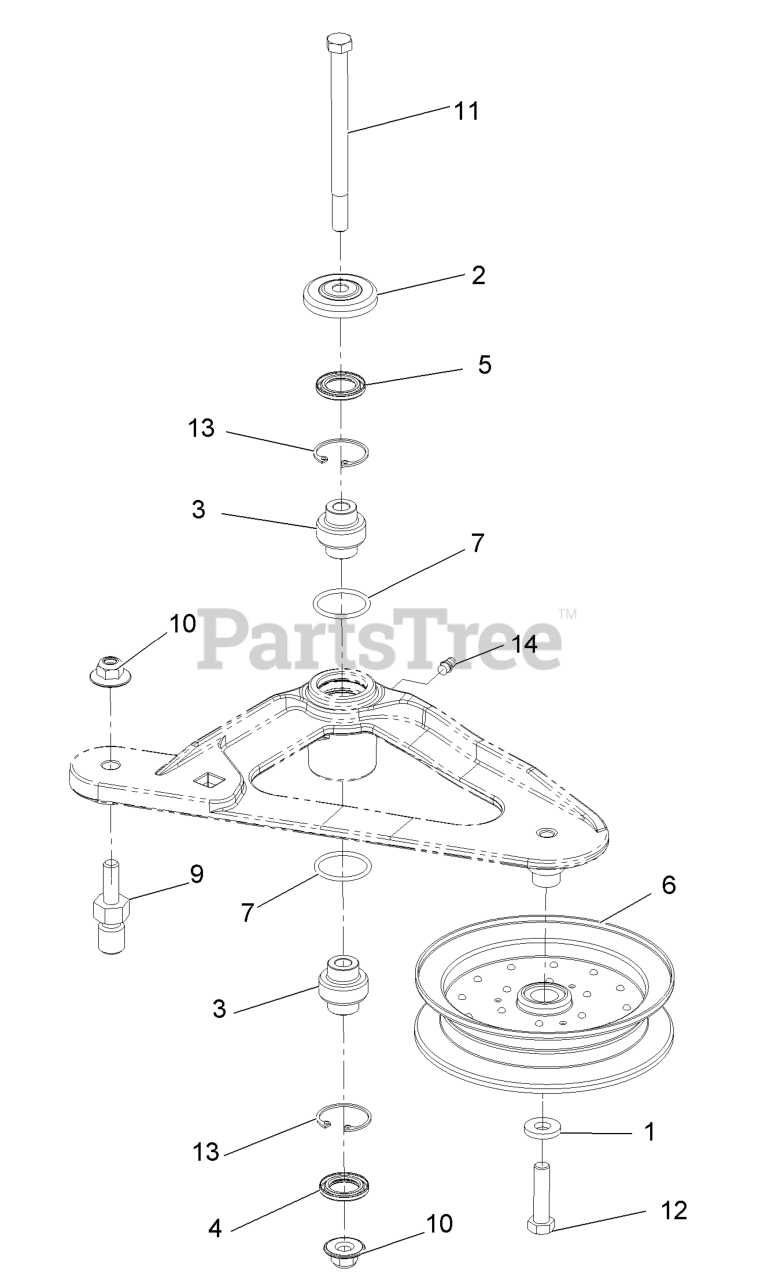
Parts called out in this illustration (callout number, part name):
2	GUARD-TOP
3	BEARING-SPHERICAL
4	SEAL-LIP, DOUBLE
5	SEAL-LIP, SINGLE
10	Nut-Nyloc 3/8-16 Flg
11	SCREW-SHOULDER, HH
12	SCREW-HH
13	RING-SNAP
14	FITTING-GREASE
